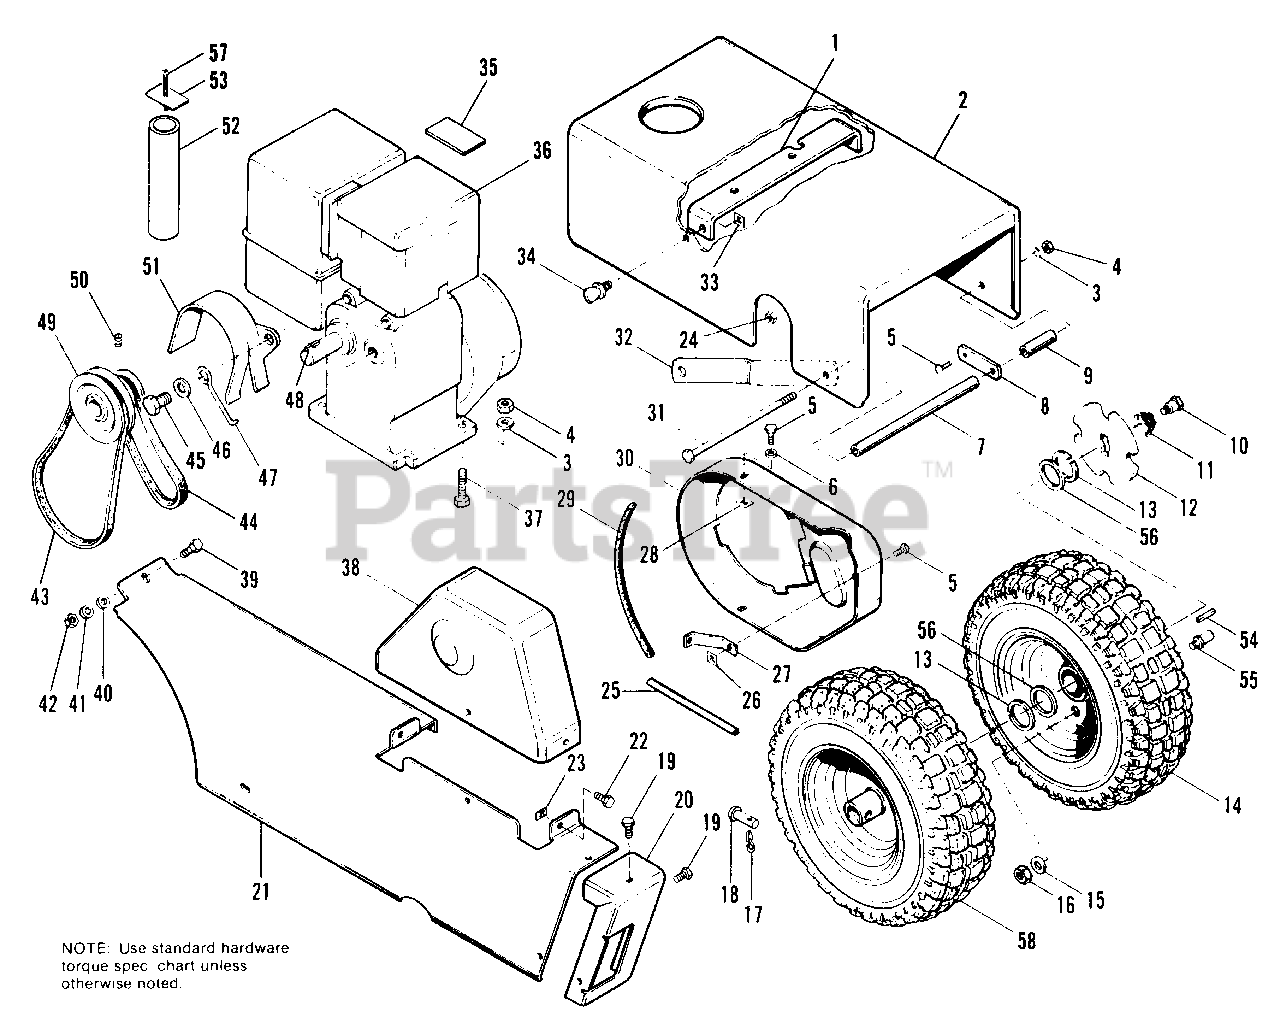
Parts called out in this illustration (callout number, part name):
1	SUPPORT, Hood
1	SUPPORT, Hood (990656 Only)
2	HOOD ASSY.
3	LOCKWASHER, 5/16
4	NUT, Hex, Full, 5/16-18
5	SCREW, Self Tapping, #10 x 1/2
6	WASHER, Plain, 3/16
7	SPACER, Hood, L.H.
9	SPACER, Hood, R.H.
10	BOLT, Shoulder
13	RING, Retaining
13	RING, Retaining (990656 & 990869 Only)
14	WHEEL & TIRE ASSY., R.H.
14	WHEEL & TIRE ASSY. (990656 Only)
14	WHEEL & TIRE ASSY. (990869 Only)
15	WASHER, Plain, 5/16
16	LOCKNUT, Hex, 3/8-16
17	PIN, Clip
18	PIN
19	SCREW, Taptite, 1/4-20 x 3/8
20	SUPPORT, Belt Cover
21	COVER, Lower Belt
22	SCREW, Self Tapping, 1/4-20 x 5/8
23	NUT, Speed
24	LOCKNUT, Conduit, 3/4
25	SEAL, Cover
26	NUT, Speed
27	BRACKET, Cover
28	NUT, Speed
29	SEAL, Cover
31	BOLT, Hood
32	BRACE, Hood
33	NUT, Retainer, 5/16-18
34	SCREW, Thumb, 5/16-18 x 3/4
35	GASKET, Felt
37	CAPSCREW, Hex Hd., 5/16-18 x 1-3/4
38	COVER, Top Belt
39	CAPSCREW, Hex Hd., 1/4-20 x 1/2
40	WASHER, Plain, 1/4
41	LOCKWASHER, 1/4
42	NUT, Hex, Full, 1/4-20
43	V-BELT (Auger Drive)
44	V-BELT (Transmission Drive)
45	CAPSCREW, Hex Hd., 1/2-20 x 1
46	LOCKWASHER, Int., 1/2
47	GUIDE, Rod
49	PULLEY, Engine
50	SETSCREW, 5/16-18 x 3/8
51	STOP, Belt
53	CLAMP, Tube
54	KEY (990643 & 990796 Only)
55	STUD (990643 & 990796 Only)
56	WASHER, Special (990656, 990869 & 990870 Only)
57	SCREW, Machine, #10-32 x 3
58	WHEEL & TIRE ASSY., L.H.
